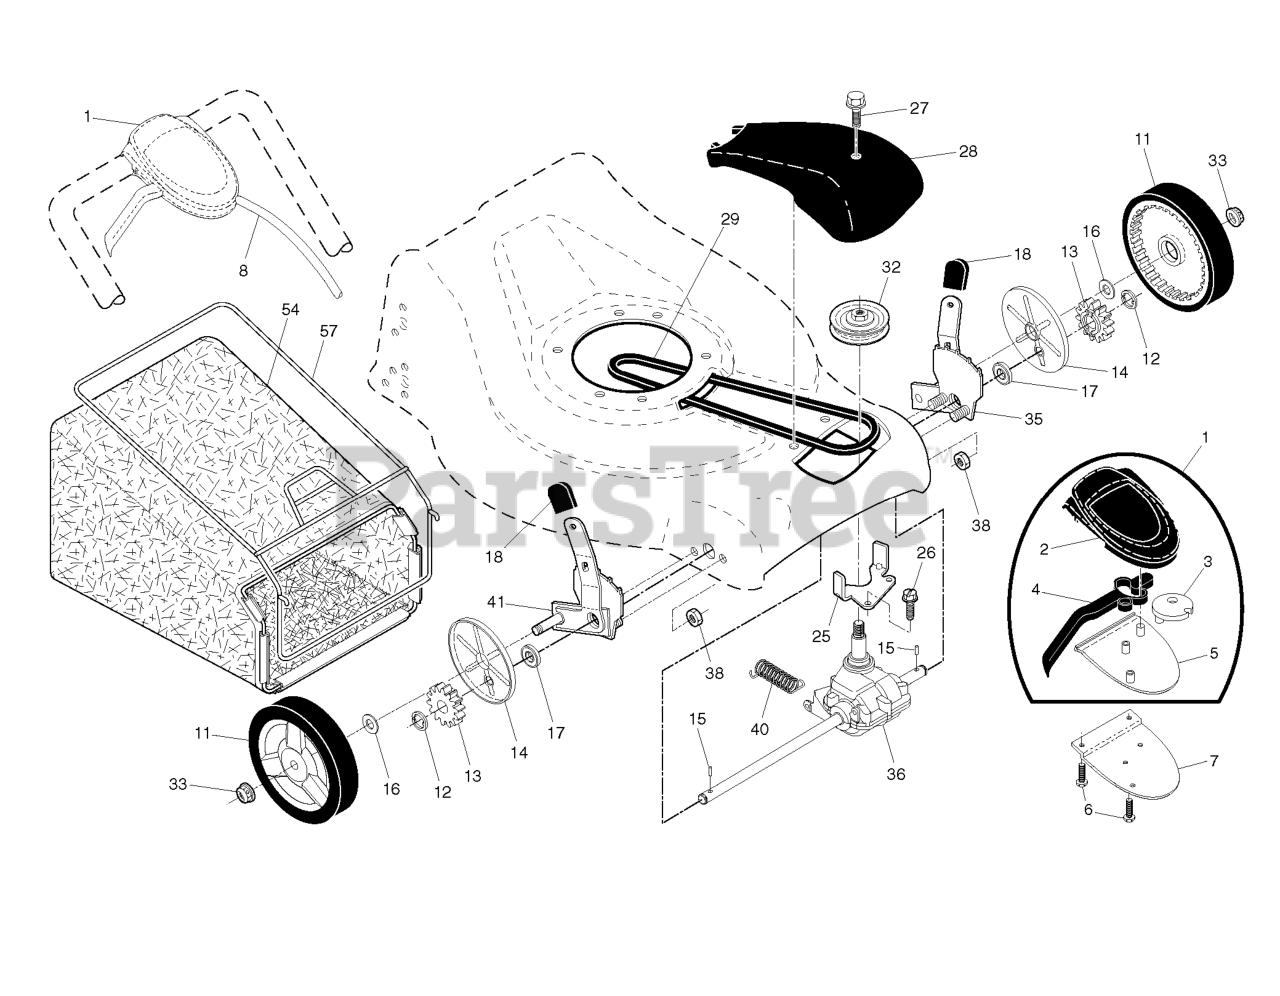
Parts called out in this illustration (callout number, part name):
1	CONTROL.DR.AW.FWGD.GRY/BLACK
2	COVER TOP AUTO WALK CONTROL
3	PULLEY.CAM.DRIVE.CONTROL.EZ
4	LEVER.SHORT.BLACK.EZ.WALK
5	COVER BOTTOM AUTO WLK CONTROL
6	SCREW, PHILLIPS HEAD 10 X 5/8
7	COVER BOTTOM AUTO WLK CONTROL
8	CABLE ASSEMBLY, DRIVE
11	WHEEL.8X1.75.H3SPK.RAD3.GY.BU3
12	E-RING 7/16 RE
13	PINION.14.TEETH.FGD
14	COVER.DUST.WHEEL
15	PAWL, DRIVE
16	WASHER FLUT
17	BEARING
18	SELECTOR KNOB
25	BELT KEEPER
27	SCREW, HEX HD TAPPING #10-24 1
28	COVER DRIVE.21.FWGD.MOLDED GRY
29	BELT.DRIVE.FG
32	RP PULLEY.DRIVE.EZ
33	NUT.HEX.FLANGE.3/8-16.LO(3 2)
35	RP KIT, WHEEL ADJUSTER, LH
36	TRANSMISSION.21.FGD.HT.VST
38	LOCKNUT.NYLOC.1/4-20
41	KIT, WHEEL ADJUSTER, RH
54	RB GBAG.33230247T.SIL.HUSQ.BLU
57	FRAME.GBAG.21.FWGD
